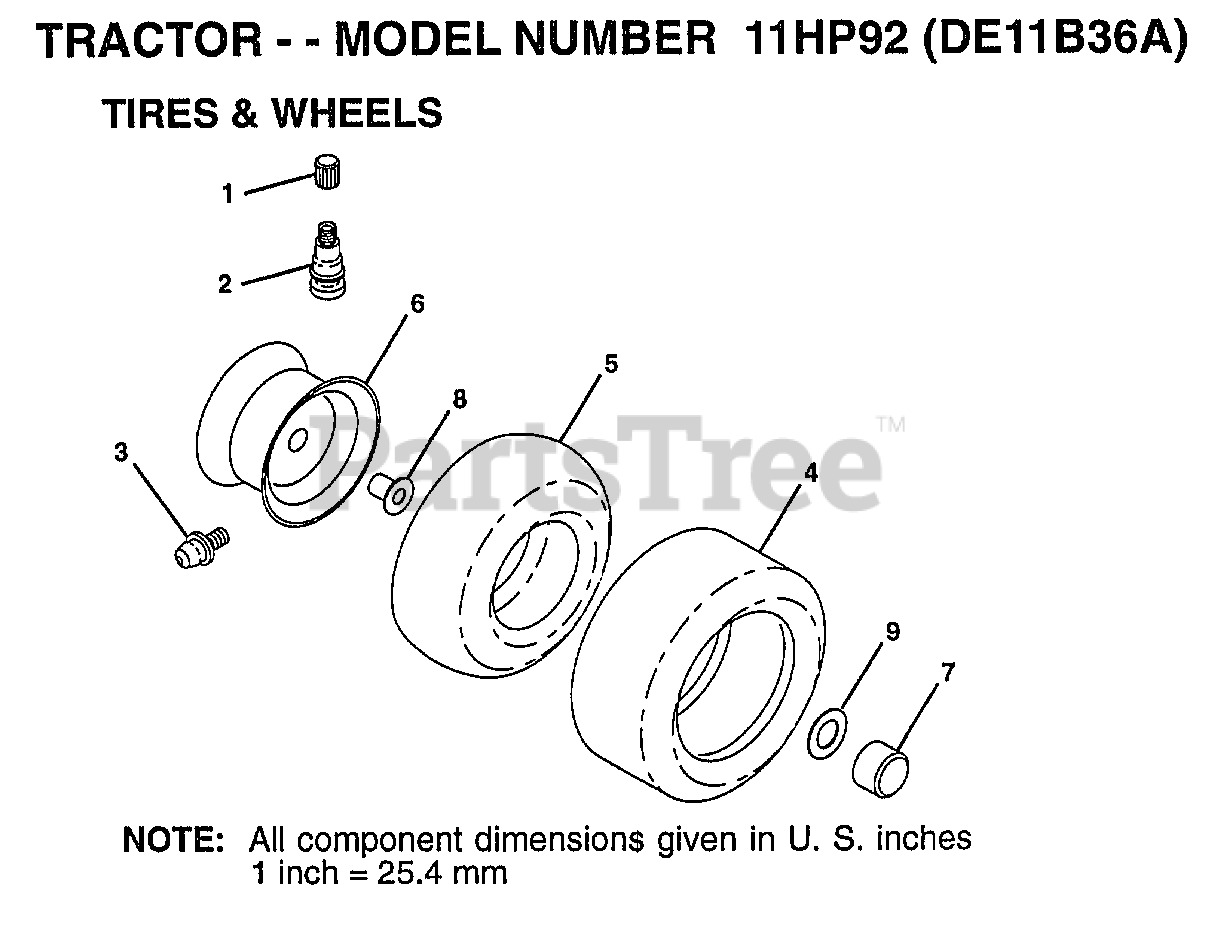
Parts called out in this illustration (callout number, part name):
1	VALVE CAP
2	VALVE STEM LT
3	FITTING LT
5	TUBE.5.3/4.5/6
5	TUBE.16X6.5/7.5-8
6	"RIM.FRT.6"".ASM"
6	"RIM REAR 8"""
7	HUB CAP
8	"FLANGE, BEARING"
9	WASHER
